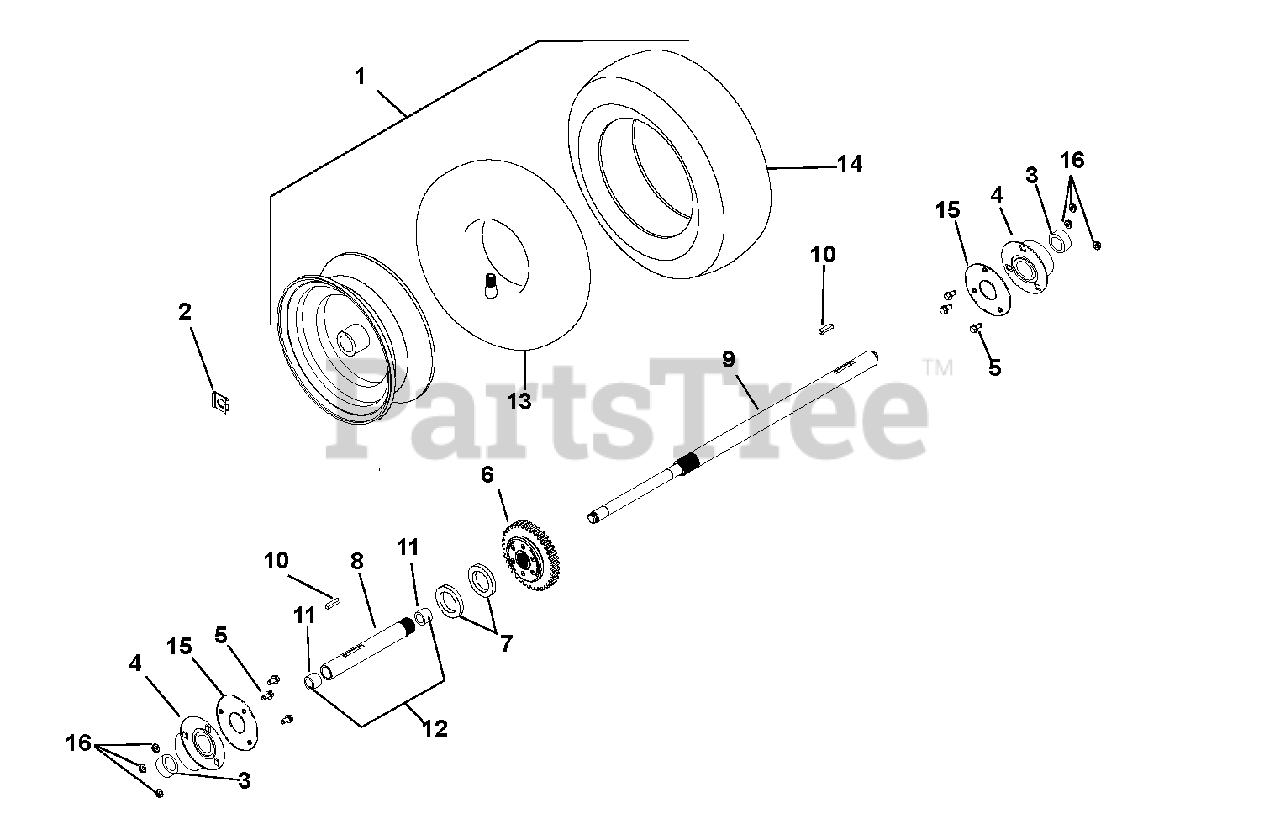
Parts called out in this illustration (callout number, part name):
1	Tire/Wheel Assembly RH 16 x 6.50-8 (Includes Item 14)
2	Clip, Snap
4	Bearing
5	Bolt, Hex .25-20 x .75
6	Differential Assembly
7	Washer, Flat Steel 1.062 x 2.00 x .134
8	Axle, Short (Included in Item 12)
9	Axle, Long
10	Key, Rectangular .25 x .188 x 1.00
11	Bushing, Sleeve (Included in item 12)
12	Axle, Short with Bushings (Includes Items 8 and 11)
13	Tube 16 x 6.50-8
14	Tire 16 x 6.50-8 K478
15	Plate, Bearing Spacer
16	Nut, Locking Top Flange .25-20
